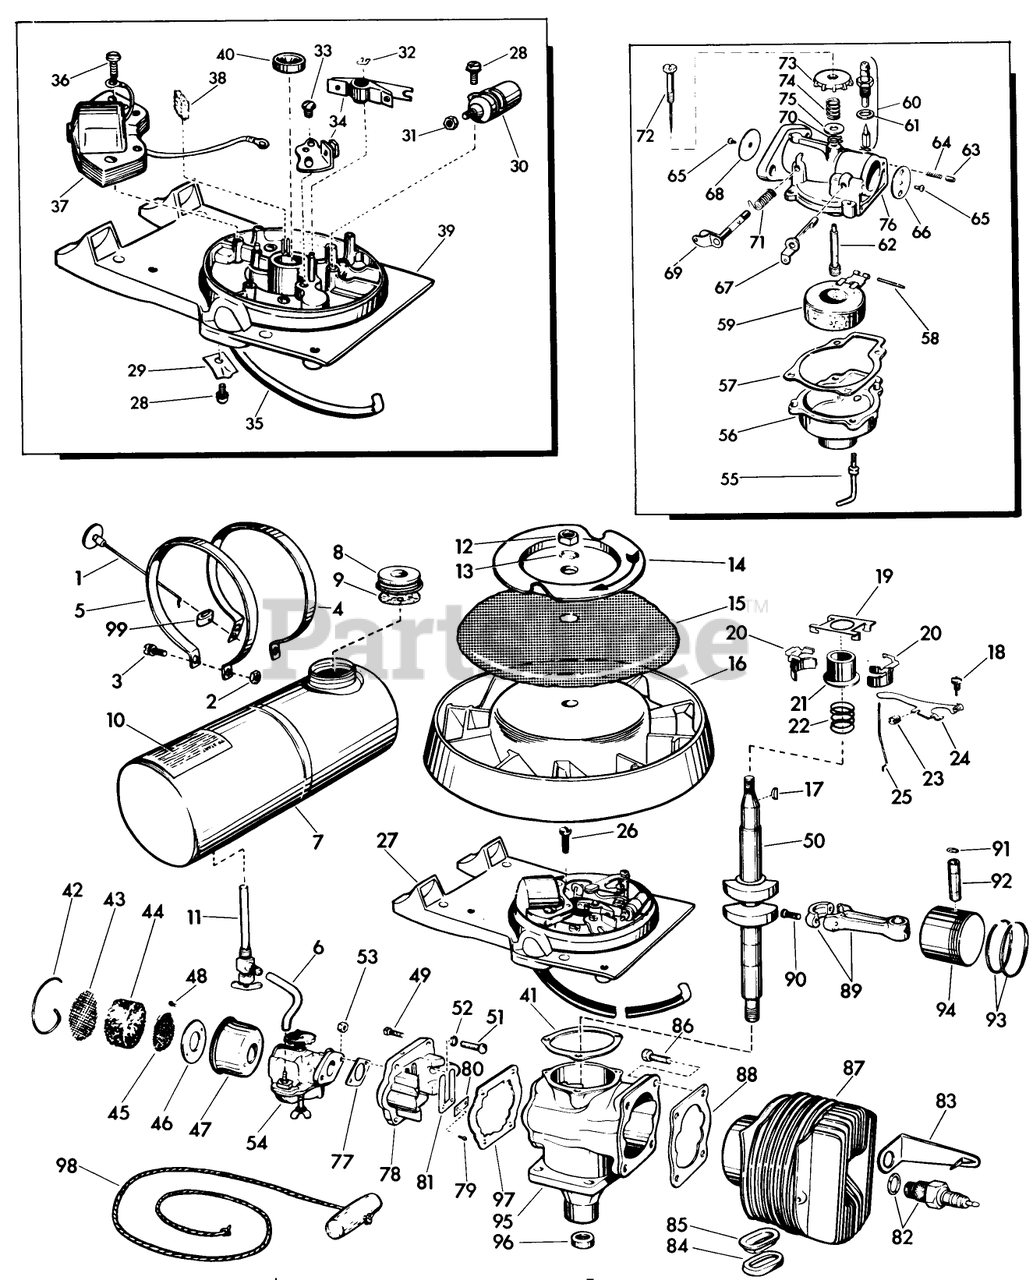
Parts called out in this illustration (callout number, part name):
2	Nut-Tank Strap Screw
3	Screw-Tank Strap
4	Strap-Gas Tank, Left
5	Strap-Gas Tank, Right
8	Gas Cap
11	VALVE&SCREEN SM
14	Pulley-Starter
15	Screen-Flywheel
21	COLLAR S
22	Spring-Governor
23	WEAR BLOCK S
24	GOVERNER LEVER AY
25	GOVERNOR ROD S
32	Spring Clip-Breaker Post
34	BREAKER AY. S
38	Oiler Wick
41	GASKET S
44	ELEMENT
46	BACK-UP PLATE
49	SCREW S
50	Crankshaft
53	STOP NUT
65	Screw-Choke Disc
71	SPRING
72	NEEDLE AY. S
74	Spring-Ndl. Adj.
77	GASKET S
80	PLATE-BACKUP, REED
82	Spark Plug
87	Cylinder Sleeve Assembly
90	Screw-Connecting Rod
93	Ring-Piston
99	Block-Friction, Knob
